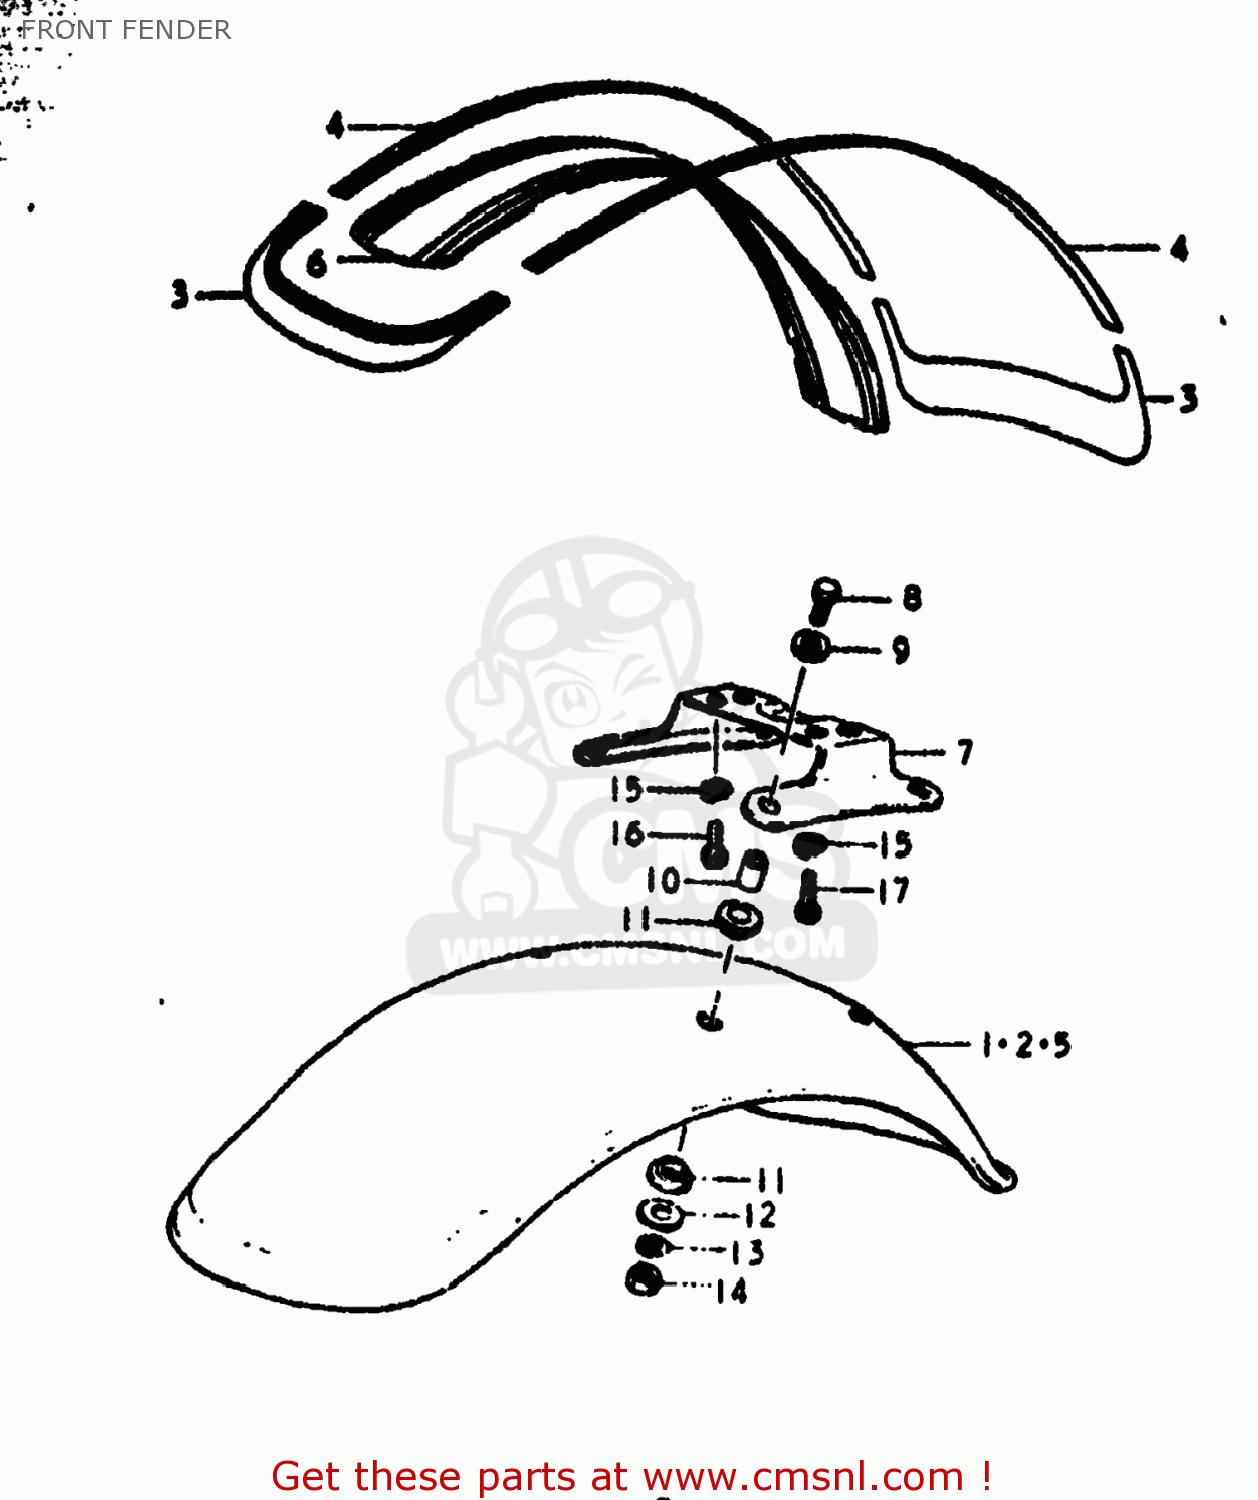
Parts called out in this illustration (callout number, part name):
1	FENDER,FRONT
2	FENDER,FRONT
3	TAPE,FRONT FENDER
4	TAPE,FRONT FENDER
5	FENDER,FRONT
6	TAPE,FRONT FENDER
7	BRACE,FRONT FENDER
8	BOLT
9	WASHER
10	SPACER (6.8X10X11.5)
11	CUSHION
12	WASHER (6.5X24X1.2)
13	LOCK WASHER
14	NUT
15	LOCK WASHER
16	BOLT
17	BOLT
